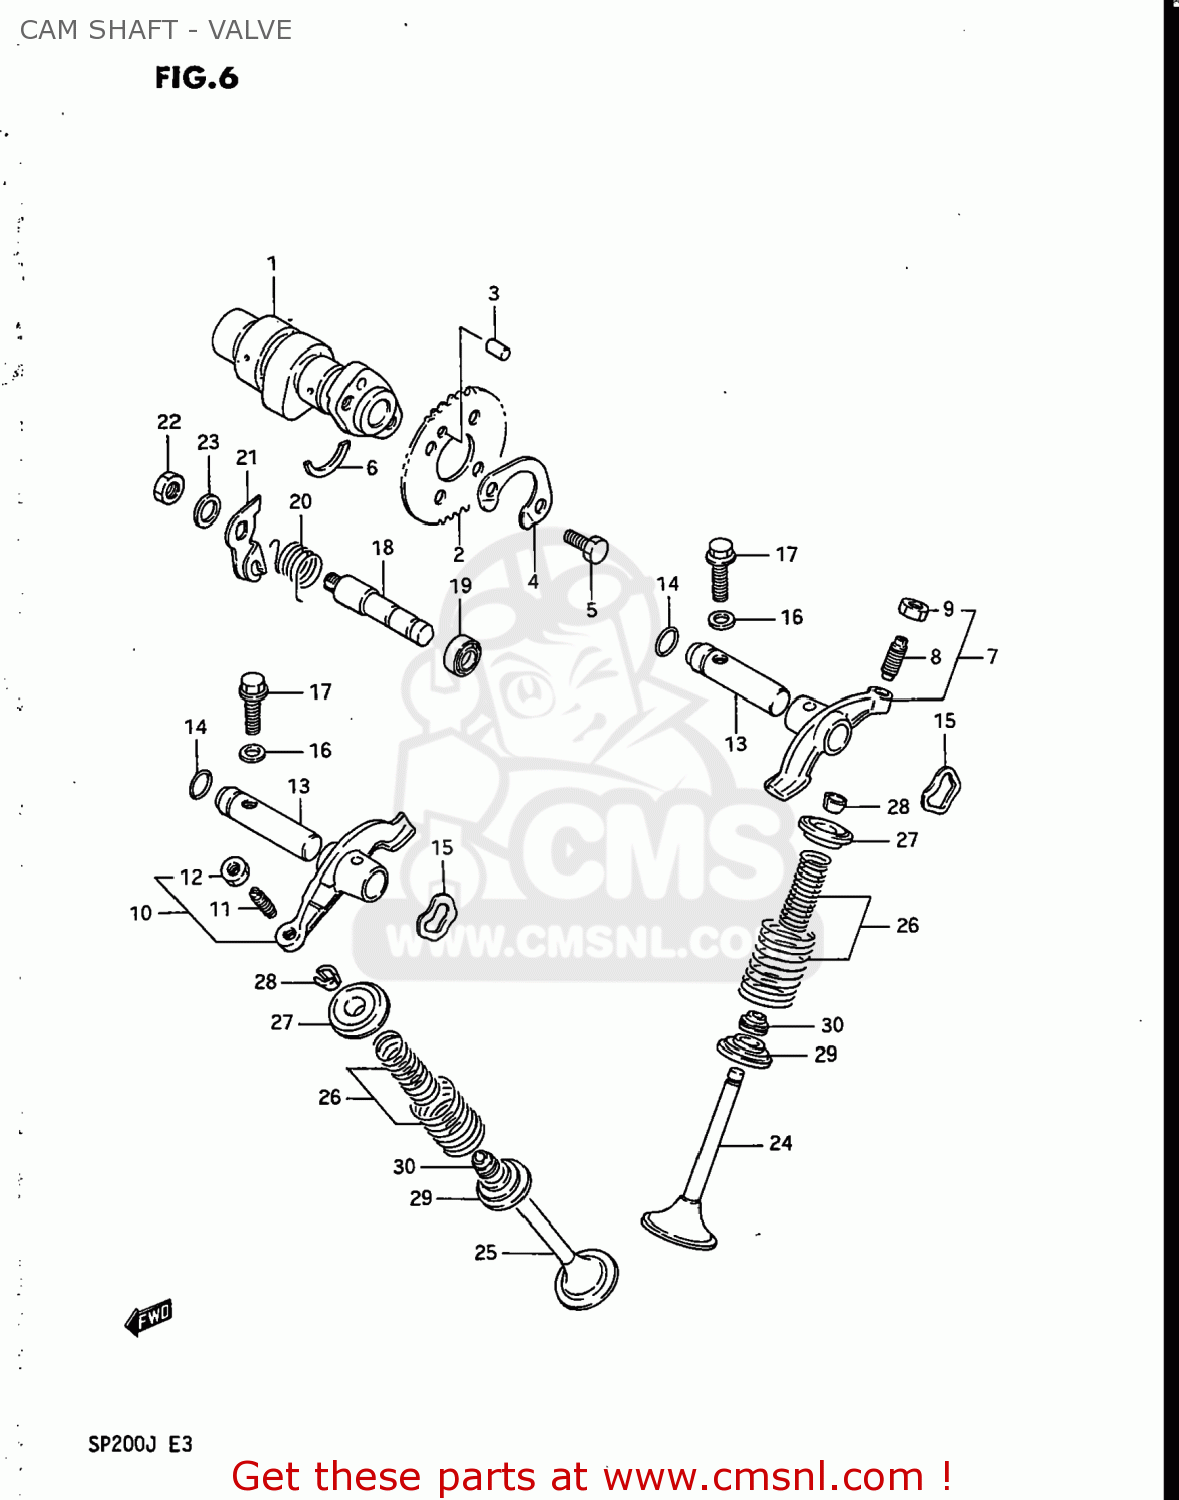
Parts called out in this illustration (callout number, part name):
1	CAMSHAFT
2	SPROCKET,CAMSHAFT
3	PIN(5X8)
4	WASHER,SPROCKET
5	BOLT(6X10.5)
6	C RING
7	ARM,VALVE ROCKER
8	SCREW,TAPPET ADJUSTING
9	NUT,ADJUSTING SCREW
10	ARM,VALVE ROCKER,EXHAUST
11	SCREW,TAPPET ADJUSTING
12	NUT,ADJUSTING SCREW
13	SHAFT,VALVE ROCKET
14	O RING(D:1.9,ID:8.6)
15	WASHER
16	GASKET(5.8X13X1.2) (NAS)
17	BOLT
18	SHAFT,DECOMPRESSION
19	OIL SEAL
20	SPRING
21	LEVER,DECOMPRESSION SHAFT
22	NUT 8MM
23	WASHER
24	VALVE,INTAKE
25	VALVE,EXHAUST
26	SPRING SET,VALVE
27	RETAINER,VALVE SPRING
28	COTTER,VALVE
29	SEAT,VALVE SPRING
30	OIL SEAL
